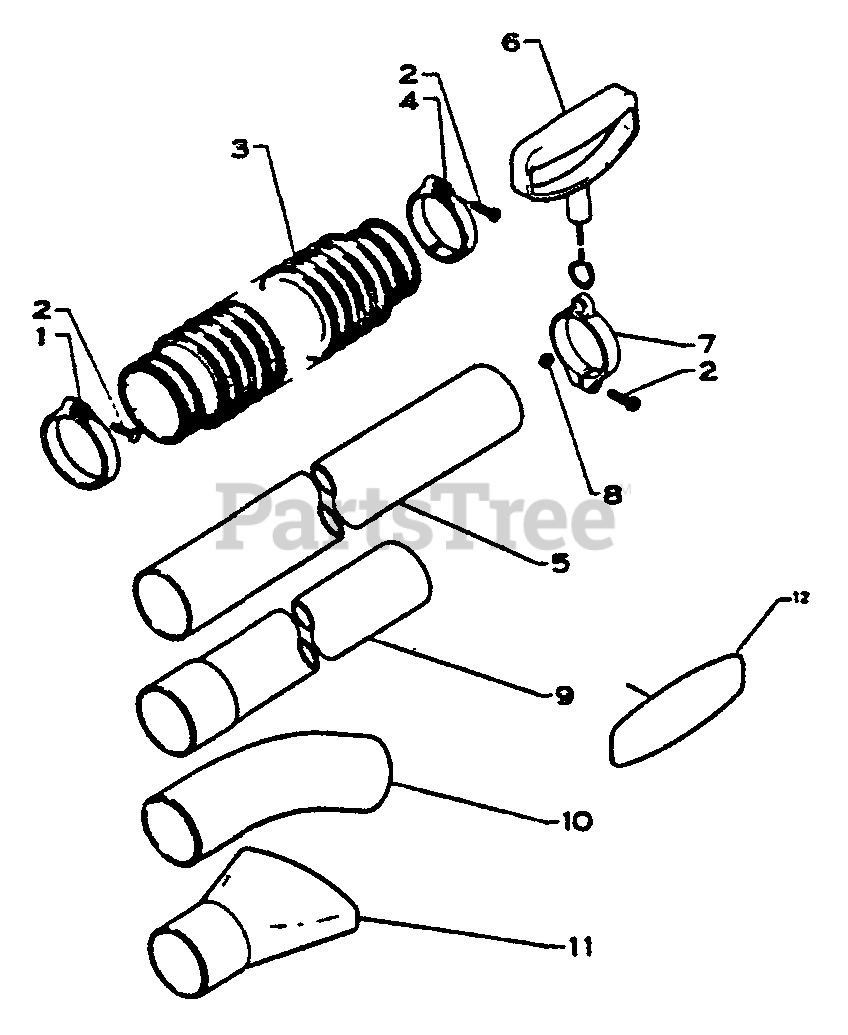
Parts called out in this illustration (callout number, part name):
1	CLAMP
2	SCREW - 5X25
3	TUBE, BLOWER - FLEXIBLE
4	CLAMP
5	TUBE, BLOWER - STRAIGHT
6	HANDLE - LEFT
7	CLAMP, HANDLE
9	TUBE, BLOWER - STRAIGHT
10	TUBE, BLOWER - CURVED
11	NOZZLE - FAN HEAD
12	LABEL - ECHO
